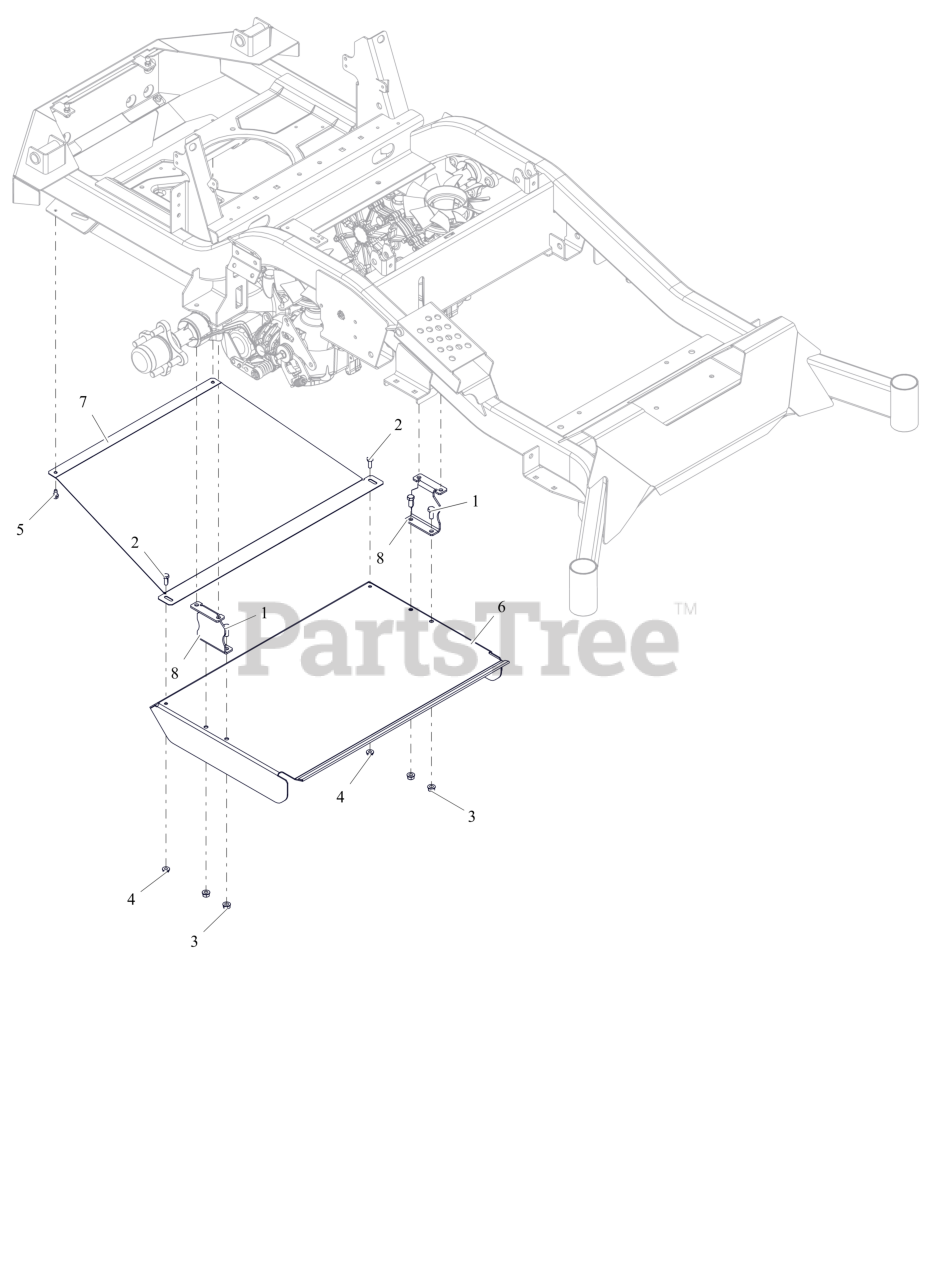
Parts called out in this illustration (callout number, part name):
1	BLT,HEX .31-18X.75 G5 ZCC
2	BLT, HEX .25-20X.75 G5 ZCC
3	NUT,LK-CTR-FLG .31-18 GF ZCC
4	NUT-LK-TOP-FLG .250-20 GF ZCC
5	SCR-TAP .25-20X.50 HWH ZCC
6	DEFLECTOR, TRANSAXLE APEX
7	DEFLECTOR, UNDERBODY
8	BRKT, DEFLECTOR SUPPORT
